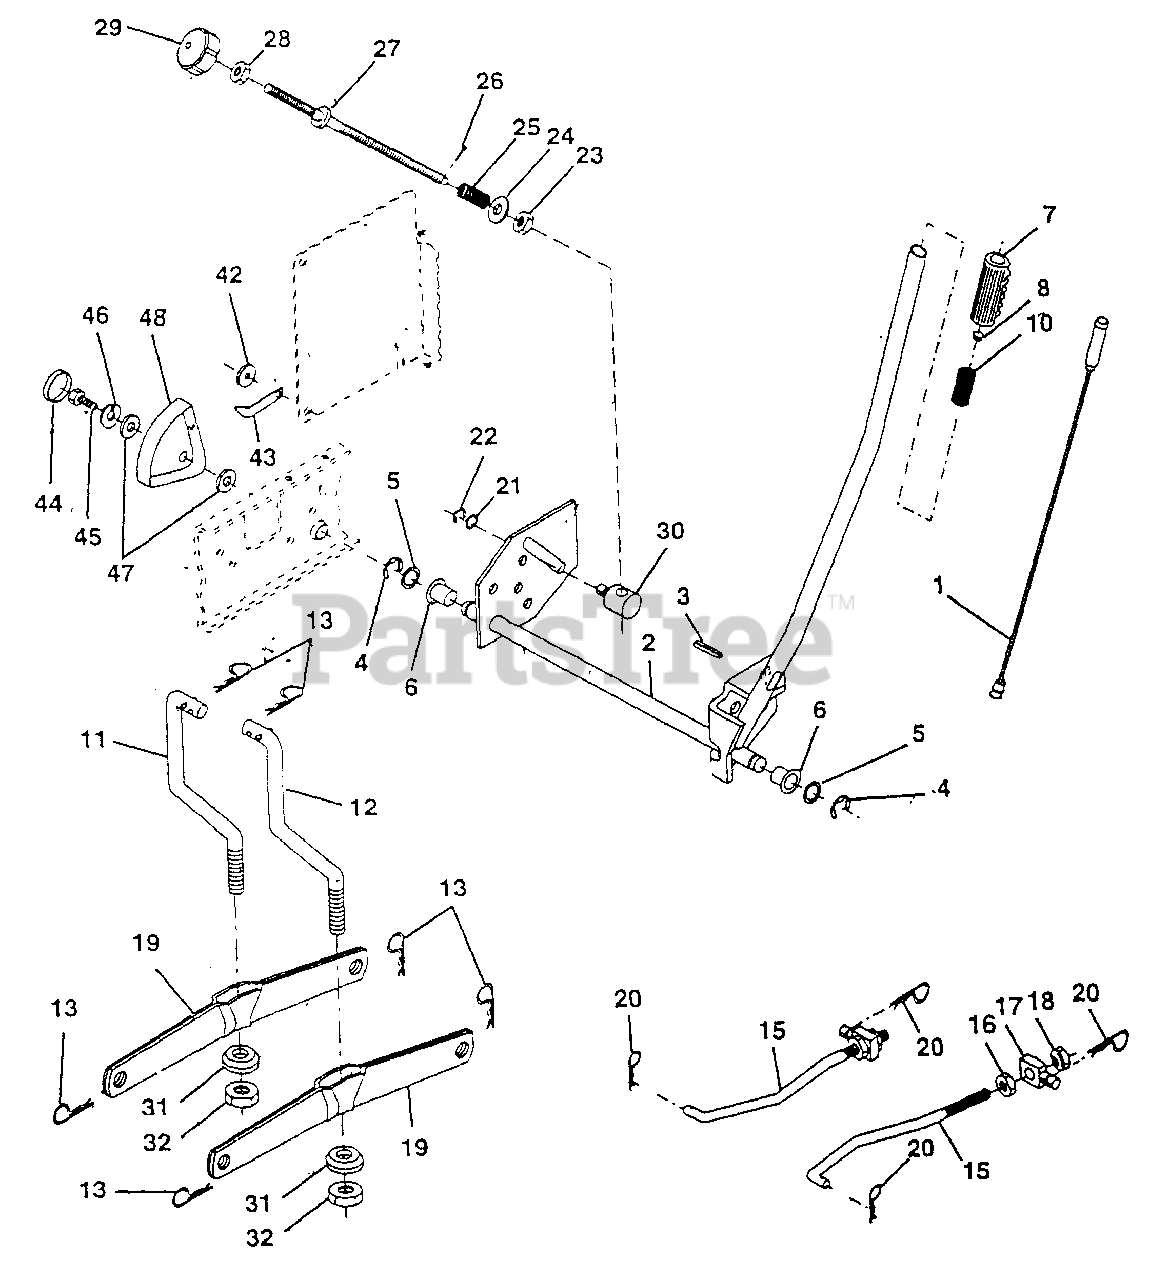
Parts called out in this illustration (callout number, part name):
1	Wire Asm Inner W/plunger 20 56
2	Shaft Asm Lift RH w/Inf W/T
3	Pin Groove 1 500 Zinc
4	E Ring #5133-62
5	Washer 21/32 X 1 X 21 Ga
6	Bearing Nylon Blk 629 Id
7	Grip Handle Fluted Blk
8	Button Plunger Black
10	Spring Cprsn 3 750 Oiled
11	Link Lift LH Fixed Length
12	Link Lift RH Fixed Length
13	Retainer Spring
15	Link Front
16	Nut Jam Hex 1/2-13 Unc
17	Trunnion Blk Zinc
18	Nut Lock W/wsh 1/2-13unc
19	Arm Suspension Rear
20	Retainer Spring
21	Washer 15/32 X 3/4 X 16 Ga
22	Ring Klip #t5304-37
23	Nut Special
24	Washer 13/32 X 5/8 X 16 Ga
25	Spring 2-1/8"
26	Pin Cotter 3/32 X 1/2
27	Rod Adj Lift Zinc 9 00 Wrk Lg
28	Nut Hex Jam 3/8-16 Unc
29	Knob Inf 3/8-16 Unc Blk W/sym
30	Trunnion Dp Stop Dbl Thds PLT
31	Bearing Pvt Lift Spherical
32	Nut Nylock 3/8 - 24
42	Washer Nylon .44 x .75 x .032
43	Pointer Pnt Height Ind .505
44	Plug Hole Blk 1.485/1.515 Dia.
45	Bolt Fin Hex 5/16 - 18 UNC x 1.00
46	Washer Lock Hvy Hlcl Spr. 5/16
47	Washer 11/32 x 1-1/2 10 Ga.
48	Scale Ind. Height Blk.
